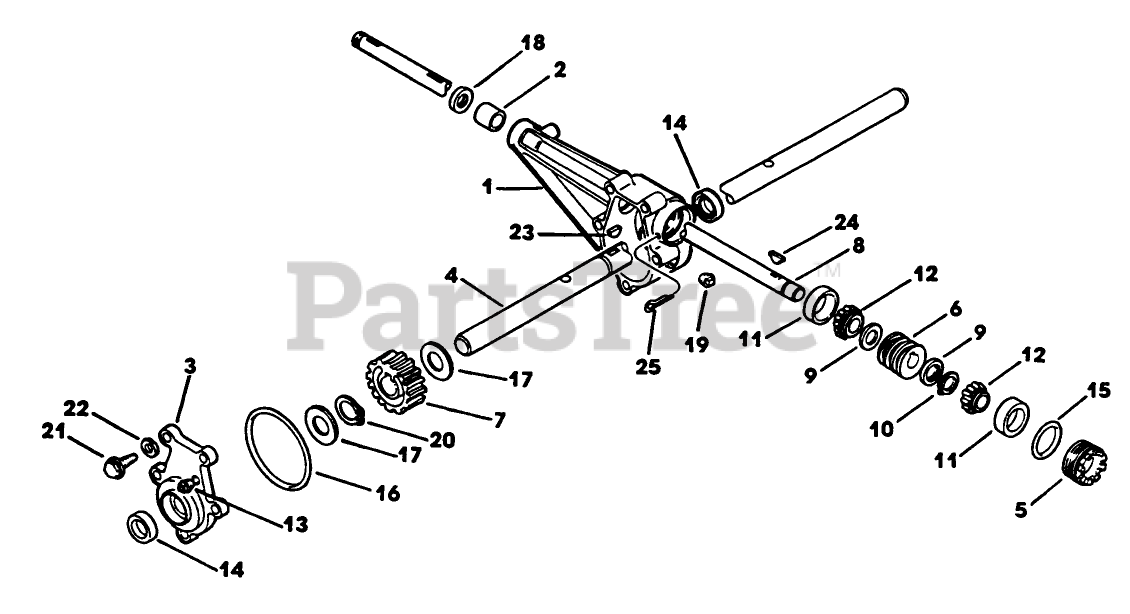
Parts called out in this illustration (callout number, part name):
1	GEAR CASE W/BUSH
5	ADJ. PLUG S
8	SHAFT-AUGER INPUT
10	RING-RETAINING
20	RING - RETAINING
